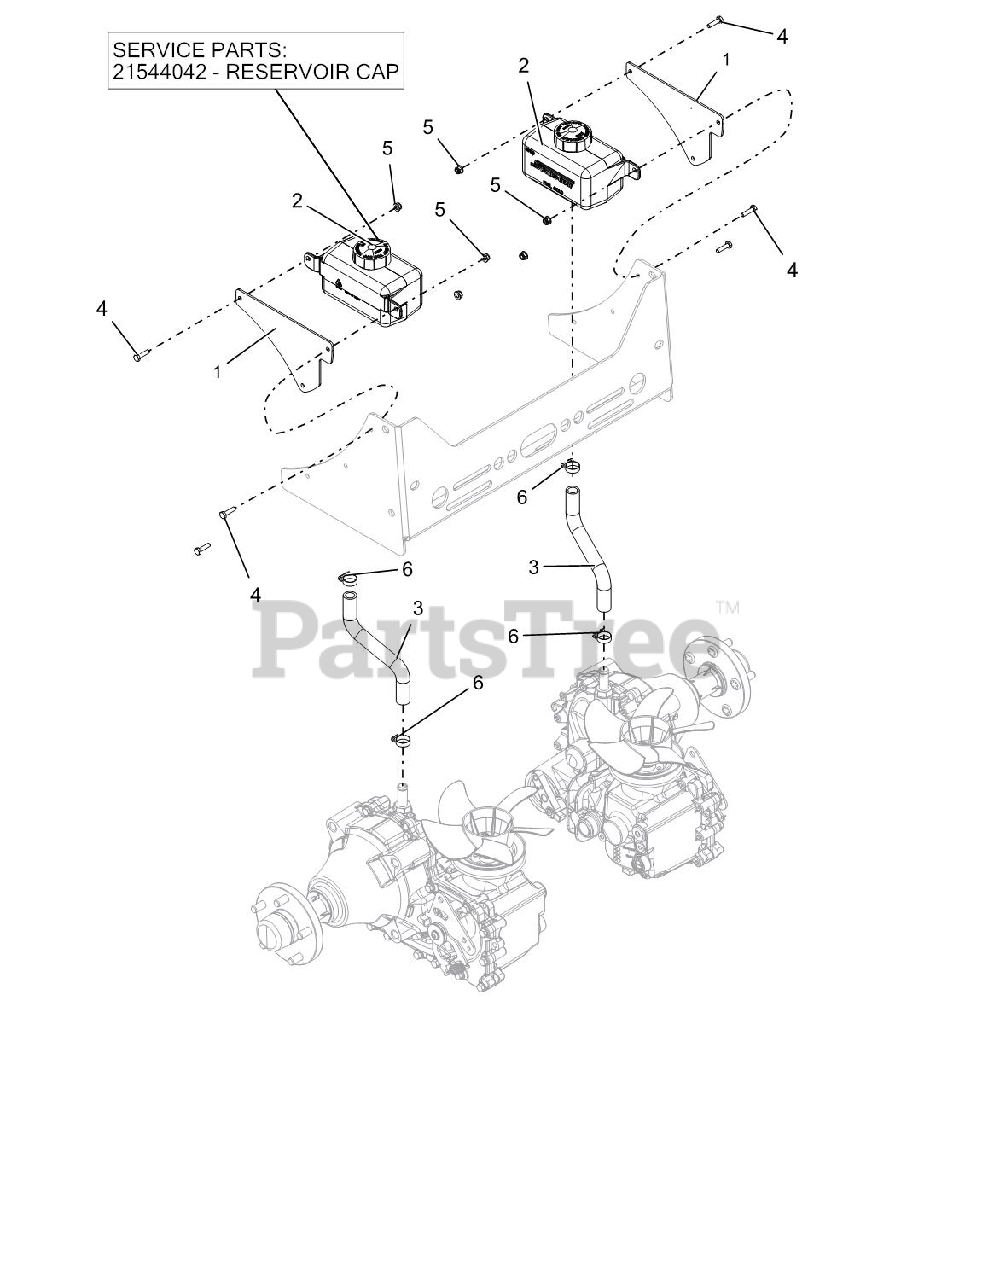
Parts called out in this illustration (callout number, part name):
1	PLATE, HYDRO OVERFLOW TANK MTG
2	TANK, HYD 1000ML
2	RESERVOIR CAP
3	HOSE, HYDRO OVERFLOW
4	BLT-HEX .25-20X1.00 GR5 YWZC
5	NUT-LK-NYL-FLG .25-20 YWZC
6	CLAMP, .88 DIA HOSE
